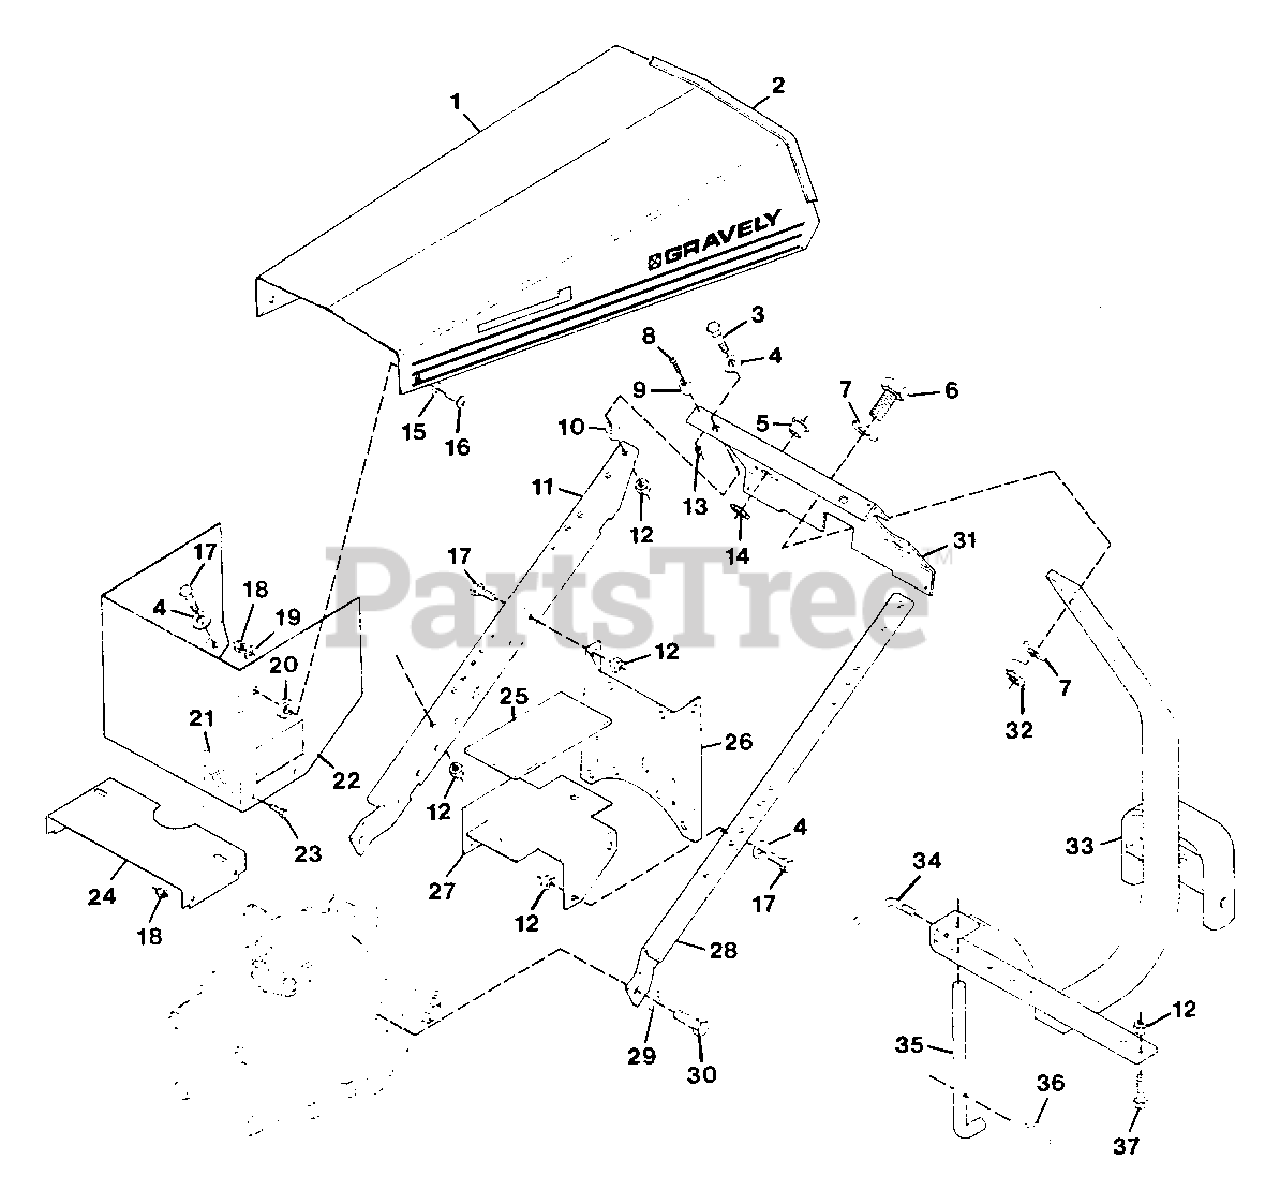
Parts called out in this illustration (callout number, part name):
1	Assembly, Hood
2	Strip, Cowl
3	Bolt, Hex 3/8-16x1.50
4	Washer, Flat .406x.812x.065
5	Bushing, .513x.750x.625
6	Bolt, Hex 5/8-11x2.00
7	Washer, Flat .656x1.250x.100
8	Screw, Mach. 6.32x.625 PHD
9	Bumper
10	Bushing, Reverse Idler
11	Support, Handlebar R.H.
12	Nut, Lock 3/8-16
13	Nut, Mach. Lock 6-32
14	Ring, Retaining
15	Washer, Flat .281x.625x.065
16	Screw, Mach. 1/4-20x1.00 PHD
17	Bolt, Hex 3/8-16x.875
18	Nut, Lock 1/4-20 (Manual)
18	Nut, Lock 1/4-20 (Electric)
19	Washer, Flat .313x.875x.065
20	Bushing, Hood
21	Decal
22	Support, Hood
23	Bolt, Hex 1/4-20x.625 (Electric)
24	Bracket (Electric)
25	Pad, Gas Tank
26	Bracket
27	Bracket, Tank Support
28	Support, Handlebar L.H.
29	Washer, Lock 1/2 Reg.
30	Bolt, Hex 1/2-13x1.00
31	Plate, Silk Screen (Manual)
31	Plate, Silk Screen (Electric)
32	Nut, Lock 5/8-11
33	Weldment, Hitch
34	Handle, Adjusting
35	Stand, Kick
36	Pin, Hair
37	Bolt, Hex 3/8-16x2.00
NS	Decal, 7240 KDE (Electric)
NS	Decal, Side Stripe
NS	Decal, Gravely
NS	Decal, 8 Lead (4-Speeds)
NS	Decal, Professional
NS	Decal, 7240 KD (Manual)
NS	Decal, Differential Lock (2-Speeds)
